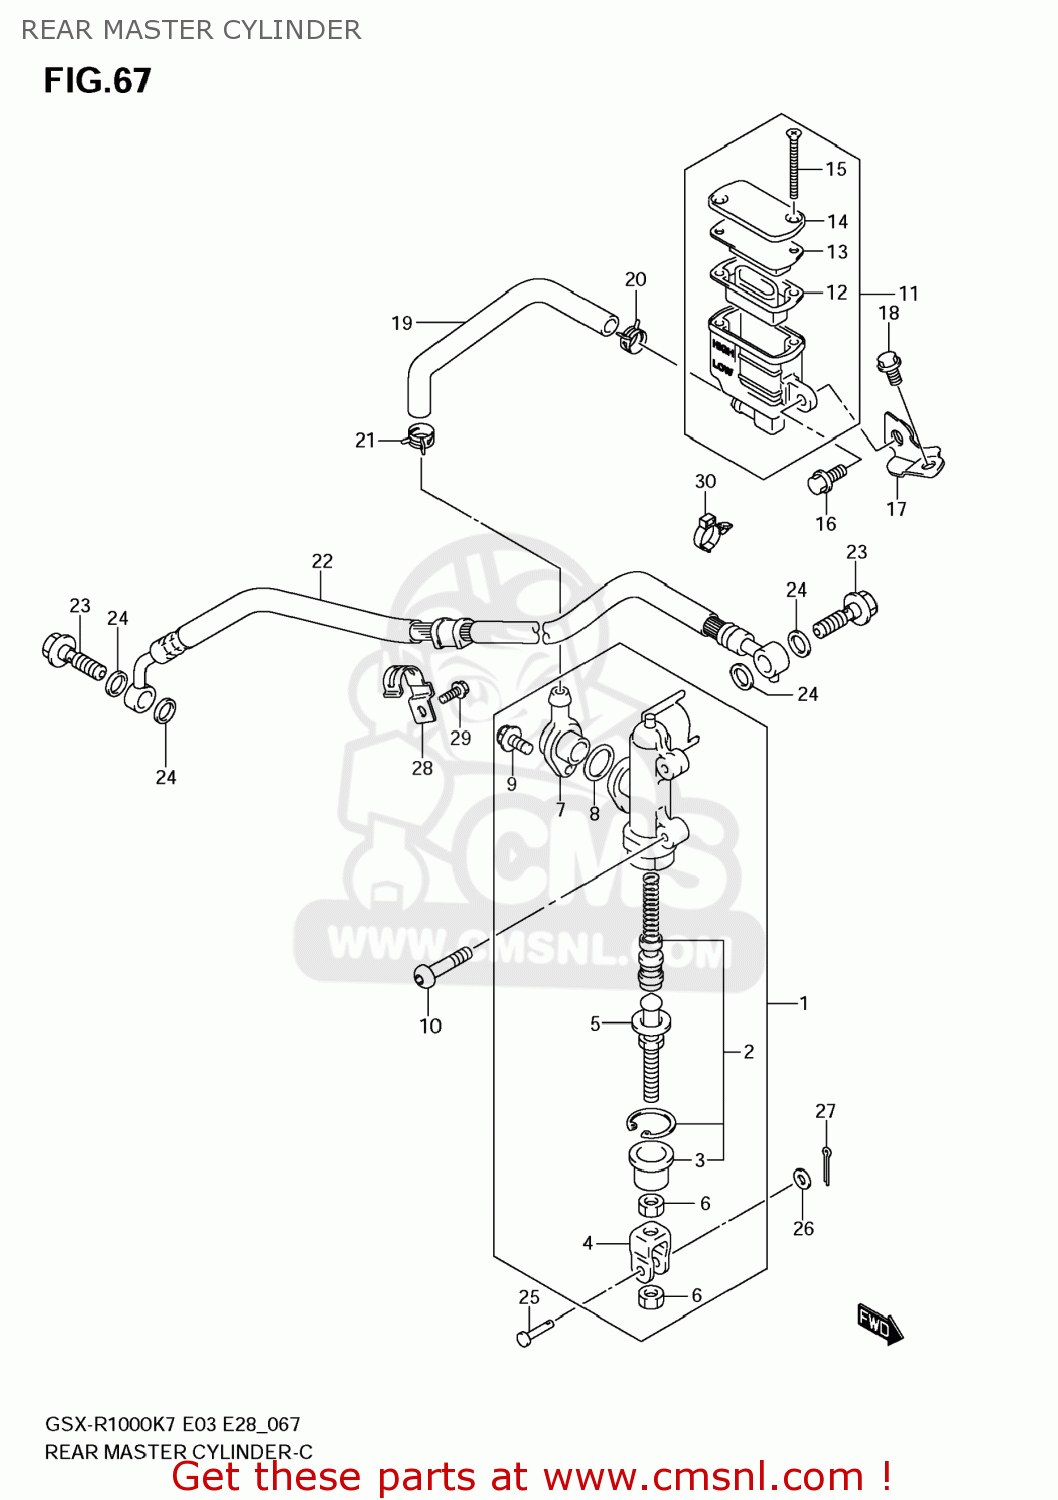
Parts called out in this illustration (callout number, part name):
1	CYLINDER ASSY,RR MASTER
2	PISTON/CUP SET
3	BOOT
4	YOKE
5	ROD,PUSH
6	NUT
7	CONNECTOR
8	O RING
9	SCREW
10	SCREW(6X20)
11	TANK ASSY,RESERVOIR
12	DIAPHRAGM
13	PLATE,DIAPHRAGM
14	CAP
15	SCREW
16	BOLT
17	BRACKET,RR RESERVOIR TANK
18	BOLT
19	HOSE,RR RESERVOIR TANK
20	CLIP
21	CLIP
22	HOSE,RR BRAKE
23	BOLT UNION
24	WASHER(10X15X1.5)
25	PIN(6X18.2)
26	WASHER
27	PIN
28	CLAMP,RR BRAKE HOSE
29	BOLT
30	CLAMP
